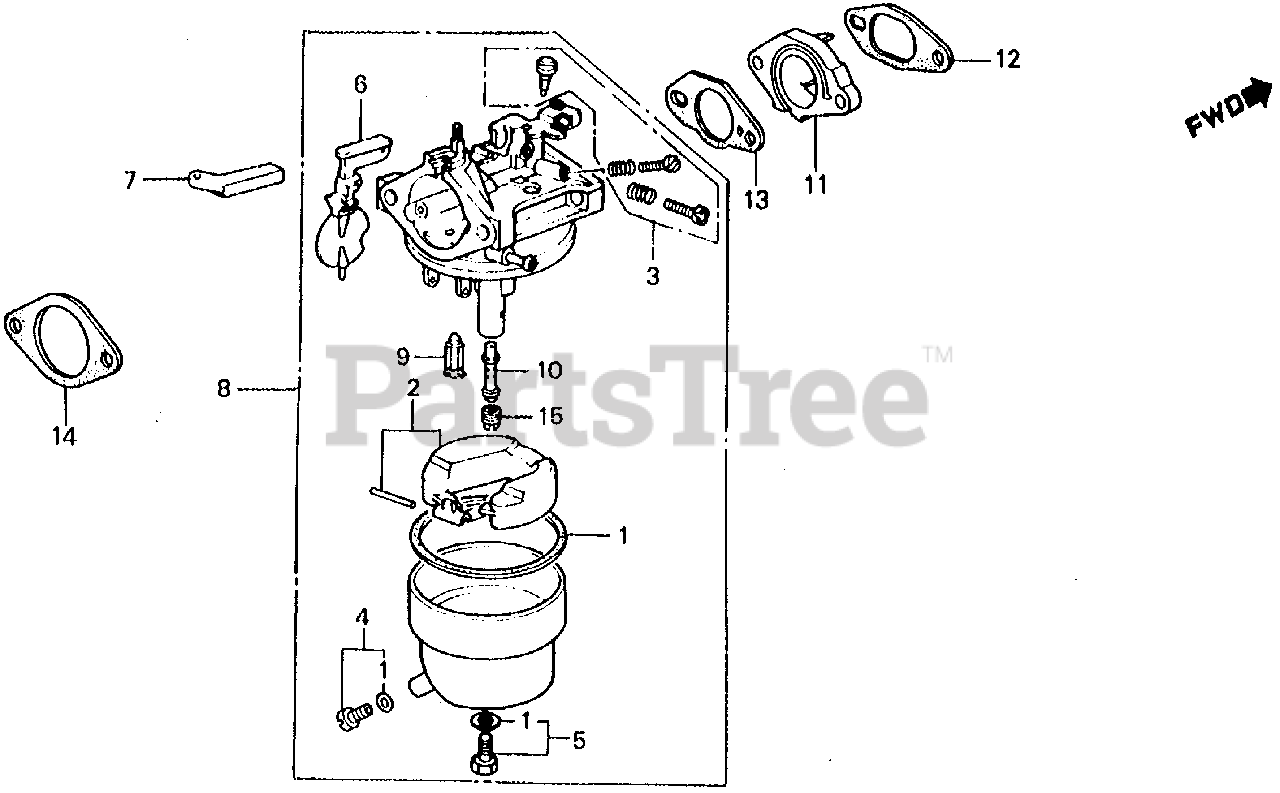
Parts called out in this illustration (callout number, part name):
1	GASKET SET
3	SCREW SET A
4	SCREW SET, DRAIN
5	SCREW SET B
7	ARM, CHOKE LEVER
8	CARBURETOR ASSY. (BB30D C)
9	VALVE, FLOAT
10	NOZZLE, MAIN
11	INSULATOR, CARBURETOR
12	GASKET, INSULATOR
13	GASKET, CARBURETOR
14	GASKET, AIR CLEANER
15	JET, MAIN (#68)
15	JET, MAIN (#70)
15	JET, MAIN (#72)
NI	CHAMBER SET, FLOAT
